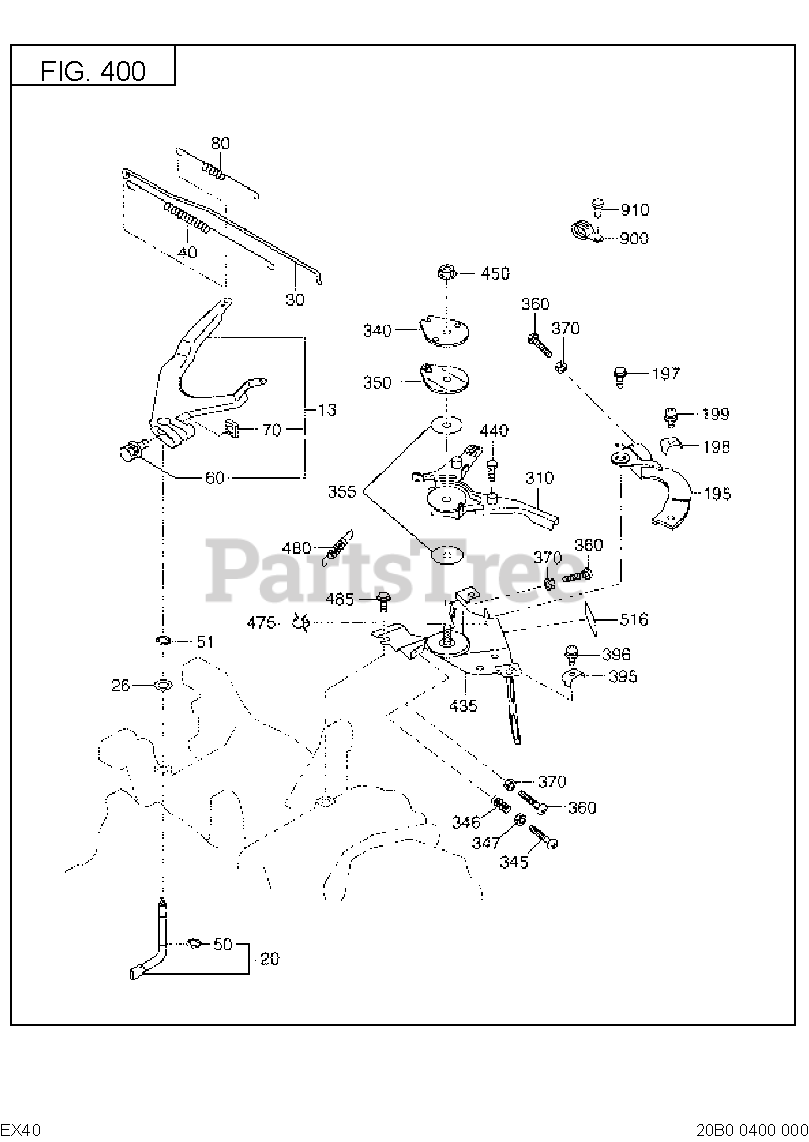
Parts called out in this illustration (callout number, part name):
13	GOVERNOR LEVER AY
20	GOVERNOR SHAFT CP
30	GOVERNOR ROD
60	BOLT AND WASHER AY
80	GOVERNOR SPRING
195	BRACKET(CHOKE)
199	SCREW AND WASHER AY
310	SPEED CONT. LEVER CP
355	FRICTION WASHER
396	SCREW AND WASHER AY
435	SPEED CONTROL BKT CP
